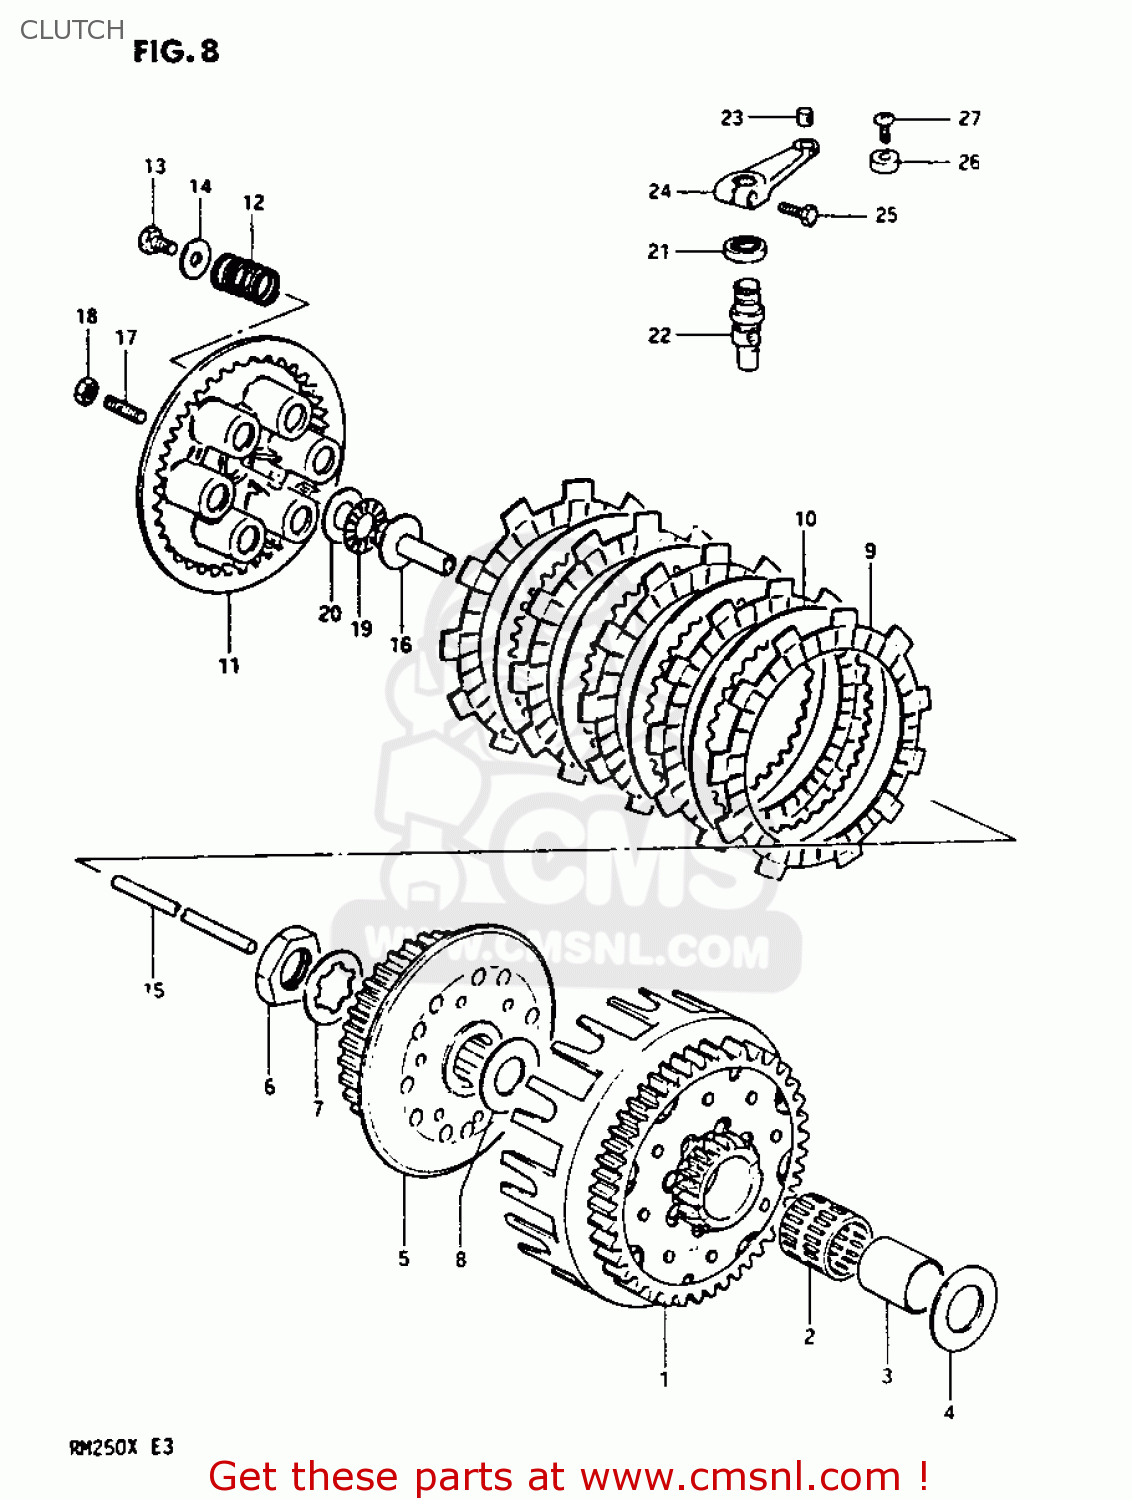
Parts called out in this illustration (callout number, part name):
1	GEAR ASSEMBLY,PRIMARY DRIVE
2	ROLLER BEARING (25X30X2
3	SPACER
4	WASHER(20X38X2)
5	HUB,CLUTCH SLEEVE
6	NUT (20MM)
7	WASHER,LOCK
8	WASHER(20X38X2)
9	PLATE,CLUTCH DRIVE (NAS)
10	PLATE,CLUTCH DRIVEN(T:2.0) (NAS)
11	DISC,CLUTCH PRESSURE
12	SPRING
13	BOLT
14	WASHER(6.5X20X1.6)
15	ROD,CLUTCH PUSH
16	PIECE,CLUTCH PUSH
17	SCREW(6X25)
18	NUT 6MM
19	BEARING(15X28X2)
20	WASHER(15.5X28X1)
21	SEAL,OIL(12X19X5)
22	SHAFT,CLUTCH RELEASE C
23	PIECE,RELEASE ARM END
24	ARM,CLUTCH RELEASE
25	BOLT
26	GUIDE,CLUTCH CABLE
27	SCREW
